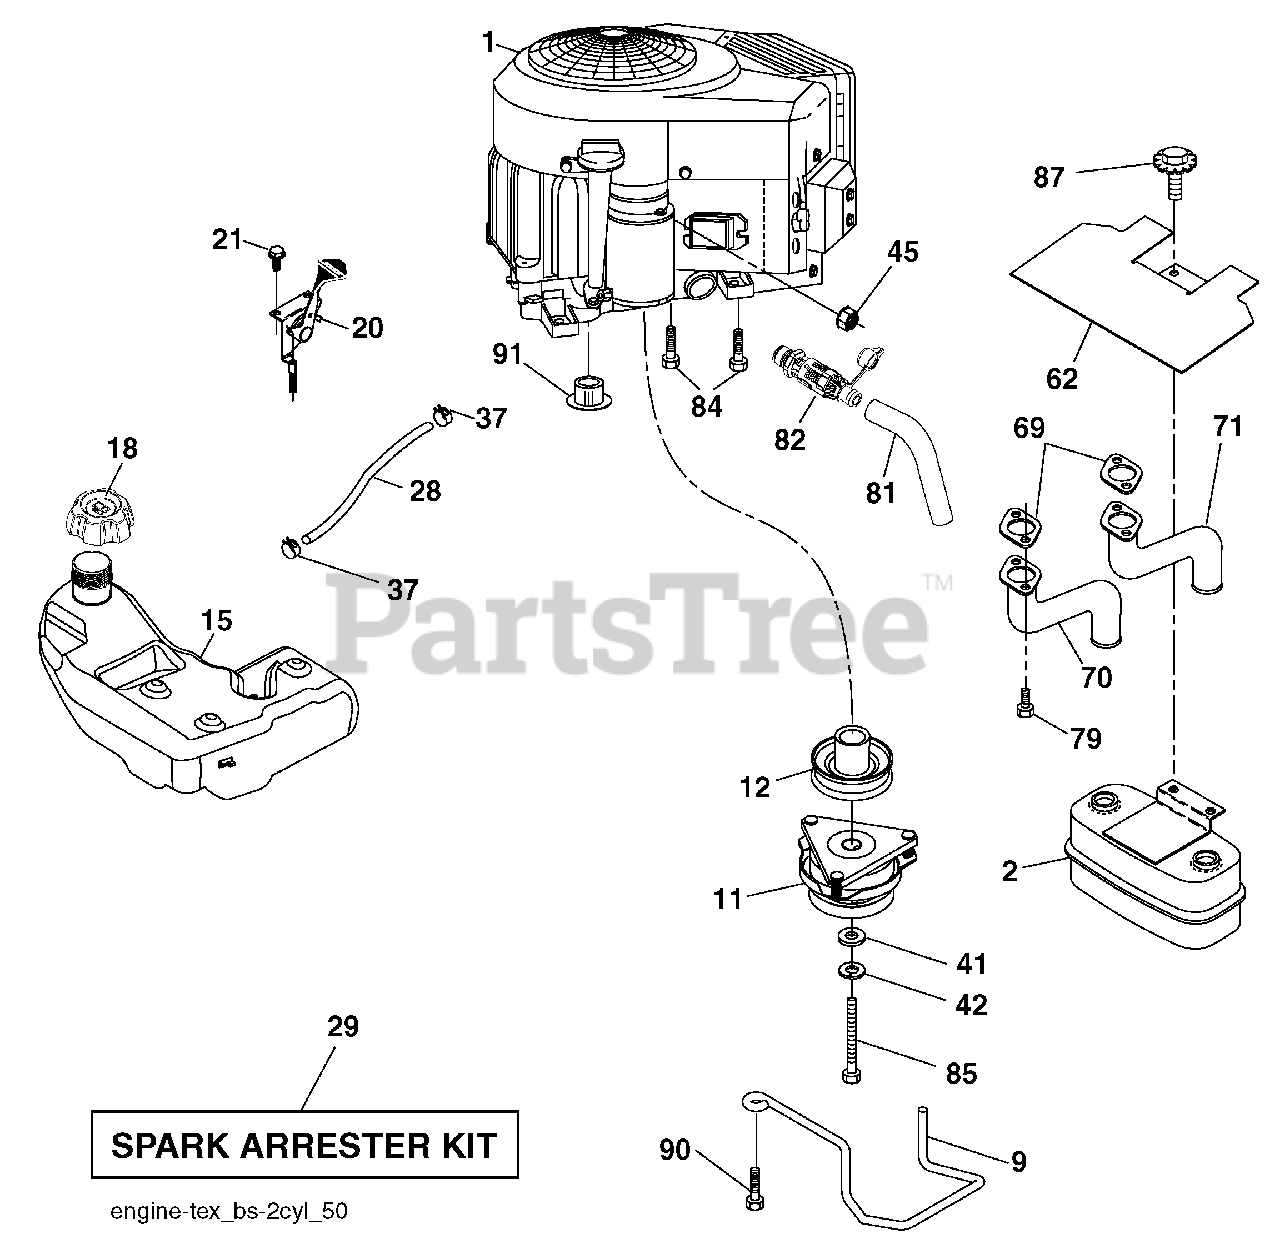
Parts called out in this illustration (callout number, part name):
2	Muffler
9	Keeper Belt Engine
11	Clutch Electric
12	Pulley Engine
15	Tank Fuel 4.0
18	Cap Asm Fuel
20	Control Throttle/CK
21	Screw #10 x .750 BOS Thread
28	Fuel Line
29	Spark Arrester Kit
37	Clamp Hose
41	Washer 1-1/2 OD x 15/32 ID x .250
42	Washer Lock 7/16
45	Nut Keps Hex 1/4-20 unc
62	Shield Heat Muffler
69	Gasket
70	Tube Exhaust LH
71	Tube Exhaust RH
79	Screw Socket Head
81	Tube Drain Oil Easy
82	Valve Drain Oil
84	Screw 3/8-16 x 1-1/4
85	Bolt Hex 7/16-20 x 3.75 Gr. 5
87	Bolt 5/16-18 unc x 1 w/Sems
90	Screw 3/8-16 x 1
91	Bushing 1.375 OD
